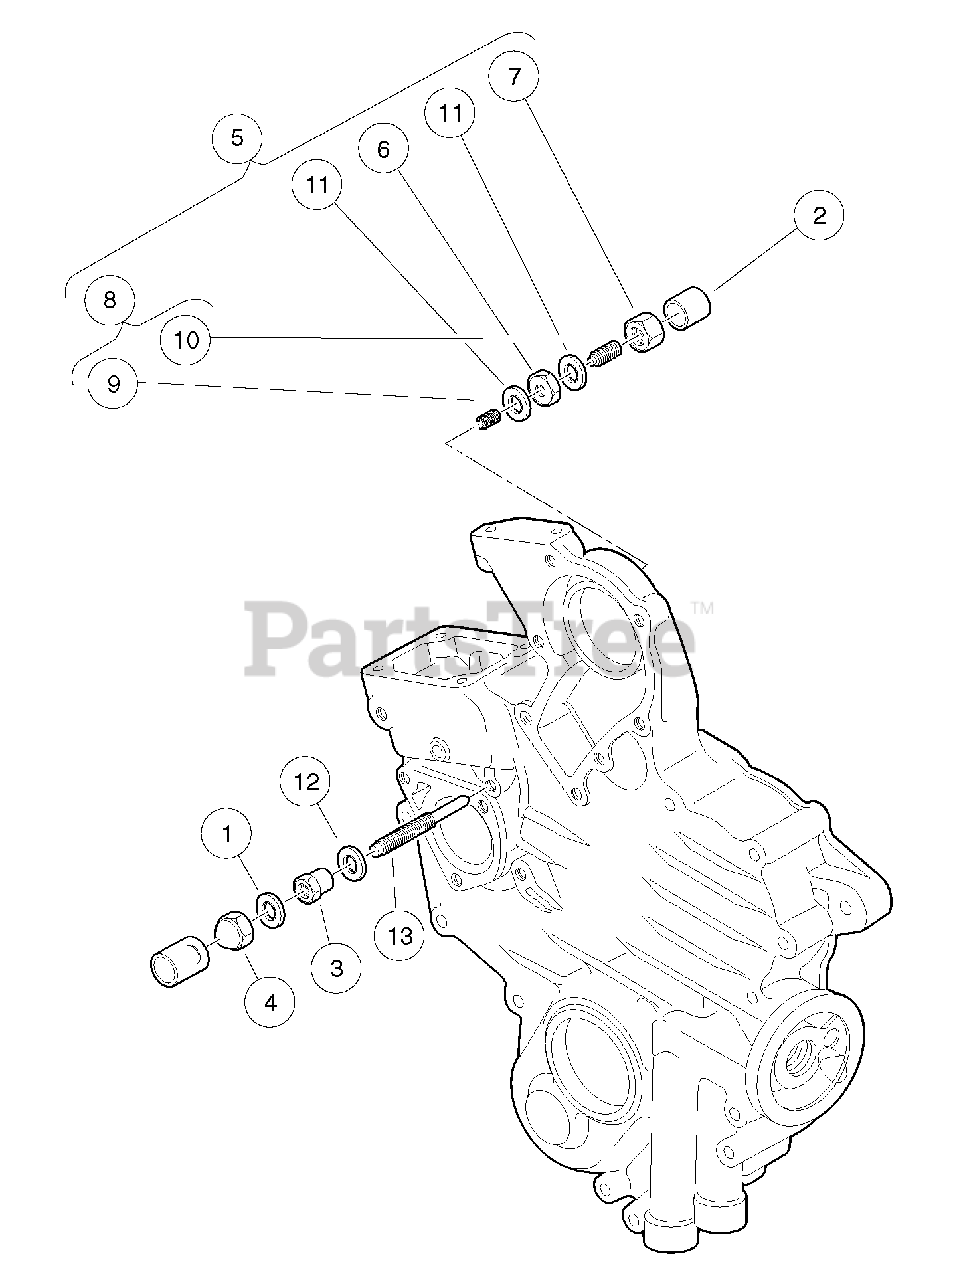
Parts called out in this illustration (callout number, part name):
1	Gasket, 6 X 10
2	Cap, Bolt Assy
3	Nut, Lock, Special
4	Nut, Special
5	Assy, Idle Apparatus
6	Nut, M8, D722 Idle App, Specl
7	Nut, M8, D722 Idle App
8	Assy, Bolt, Adjusting
9	Spring, Idle Apparatus
10	Stud, Idle Adjustment
11	Gasket, Idle Apparatus, Rear
12	Gasket, Idle Apparatus, Front
13	Bolt, Idle Adjusting
